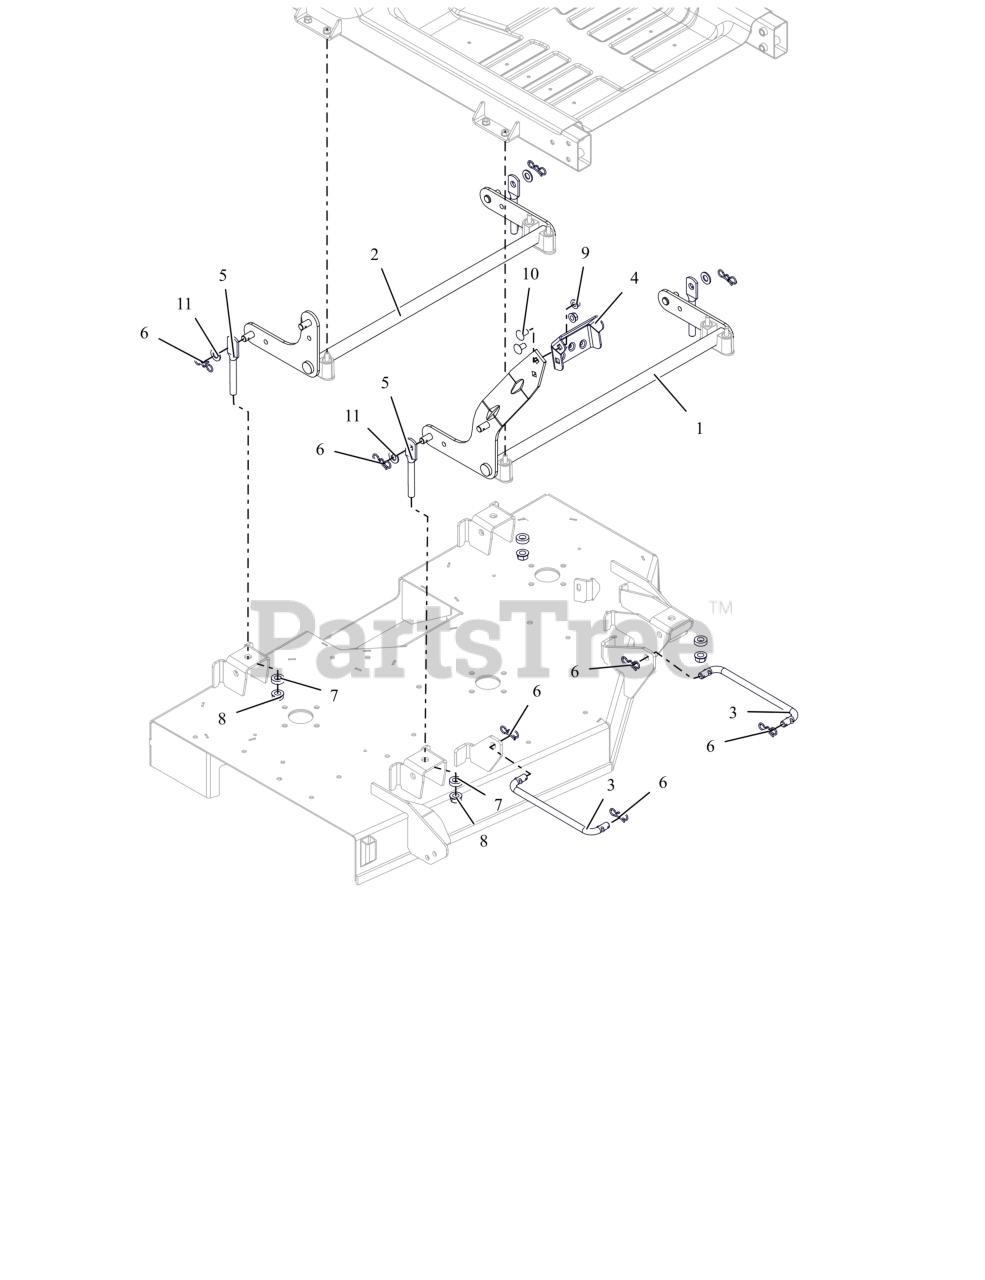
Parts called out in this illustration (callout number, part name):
1	WLDMT, FRONT DECK LIFT PIVOT
2	WLDMT, REAR DECK PIVOT
3	LINK, DRAG
4	PEDAL, DECK LIFT (BOLT ON)
5	LINK,DECK (HOLE-LONG)
6	PIN, BOWTIE .091X1.875 ZCC
7	WASHER, RUBBER
8	NUT-LK-CTR-FLG .500-13 GG ZCC
9	NUT-LK-CTR-FLG .375-16 GF ZCC
10	BTL,RHSSN .375-16 X 0.75 G5 FPB
11	WSHR-FL-NYL .518X1.000X.080
